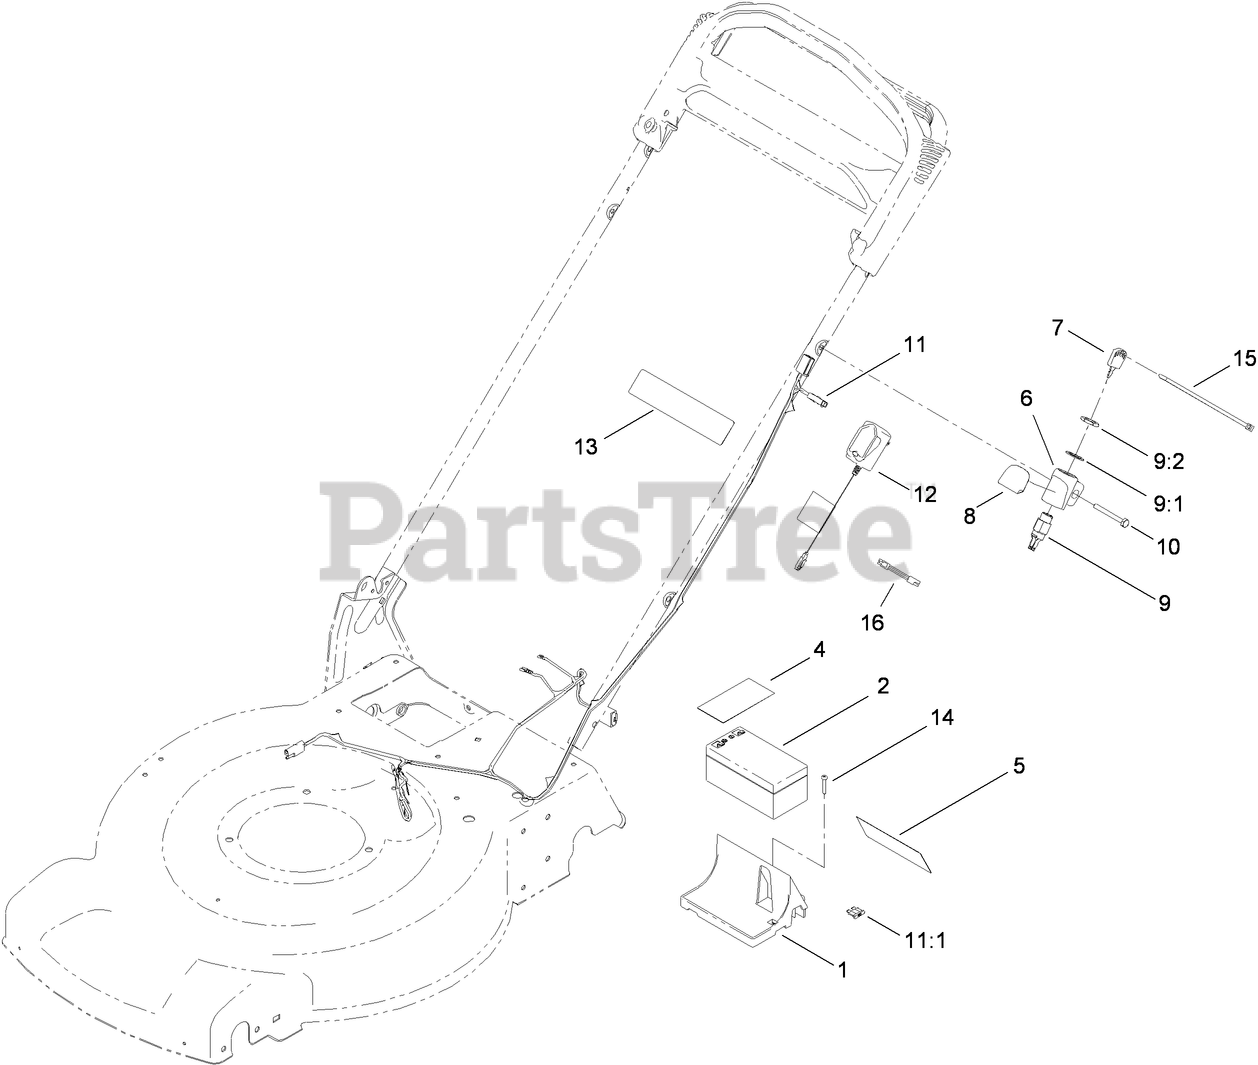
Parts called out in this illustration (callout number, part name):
1	TRAY-BATTERY
2	BATTERY-WET
4	DECAL-TERMINAL, BATTERY
5	DECAL-BATTERY TRAY
6	MOUNT-SWITCH
8	DECAL-ELECTRIC START
9	STARTER SWITCH ASM
9:1	WASHER-LOCK
9:2	NUT-HH
10	SCREW-HH
11	HARNESS-WIRE
11:1	FUSE-40 AMP
12	CHARGER-EUROPEAN, 12V DC
13	DECAL-WARNING
14	SCREW-PPH, PLASTITE
15	TIE-CABLE
16	ADAPTER-CHARGER
